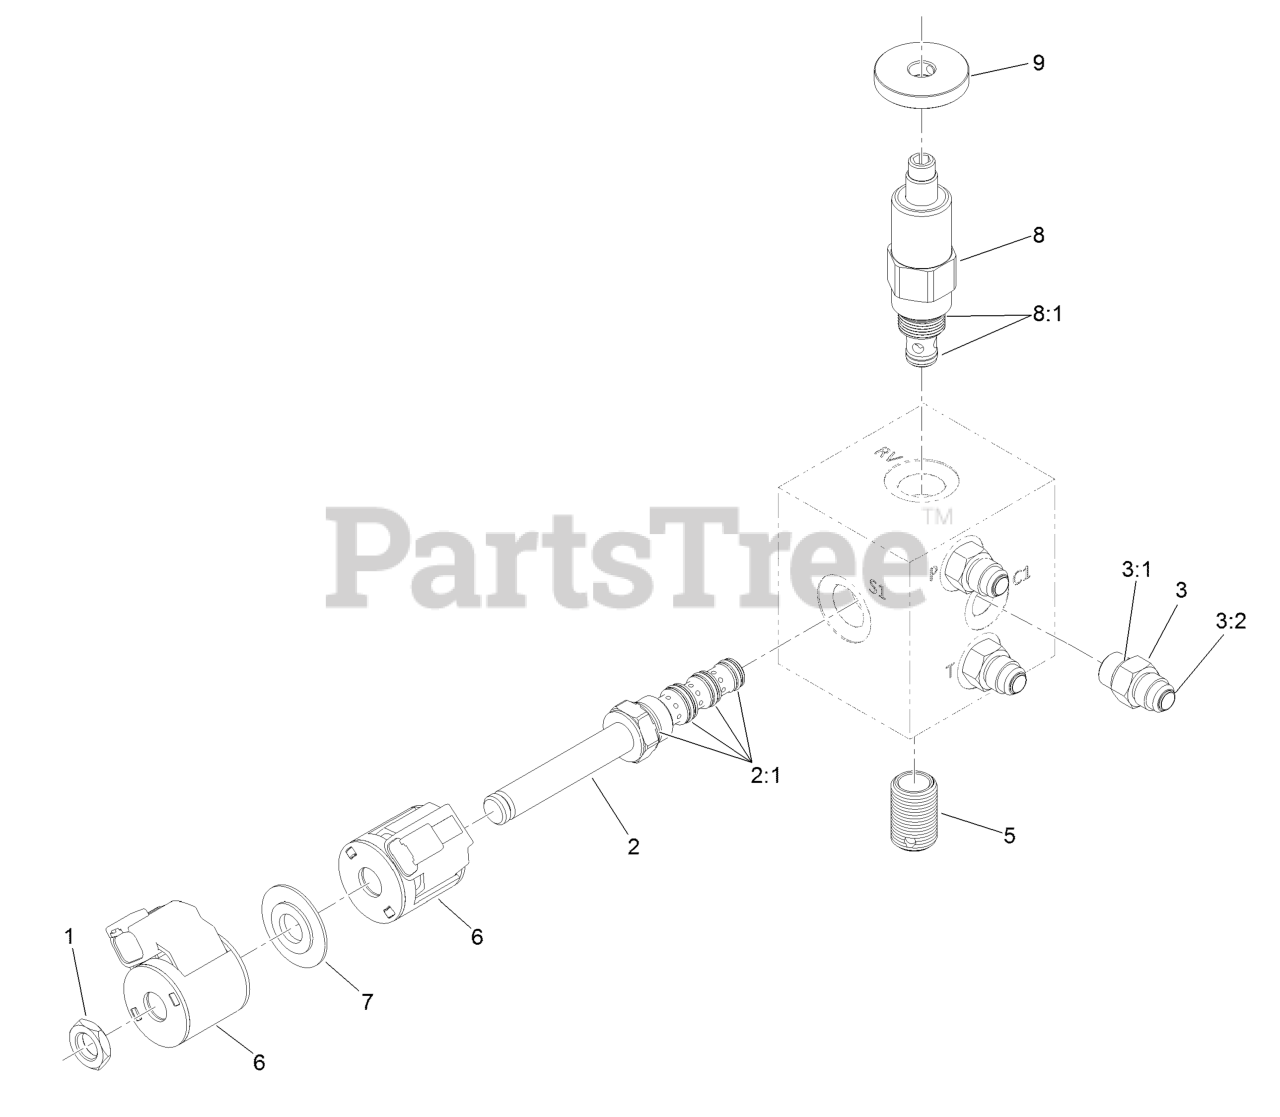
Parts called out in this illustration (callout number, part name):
1	Nut-Coil
2	Valve-Solenoid
2:1	Seal Kit
3	Fitting-Straight
3:1	O-Ring
5	Nipple-Filter
6	Coil-Solenoid
7	Spacer-Coil
8	Valve-Relief, Poppet Type
8:1	Seal Kit
9	Knob (1.5 DIA)
